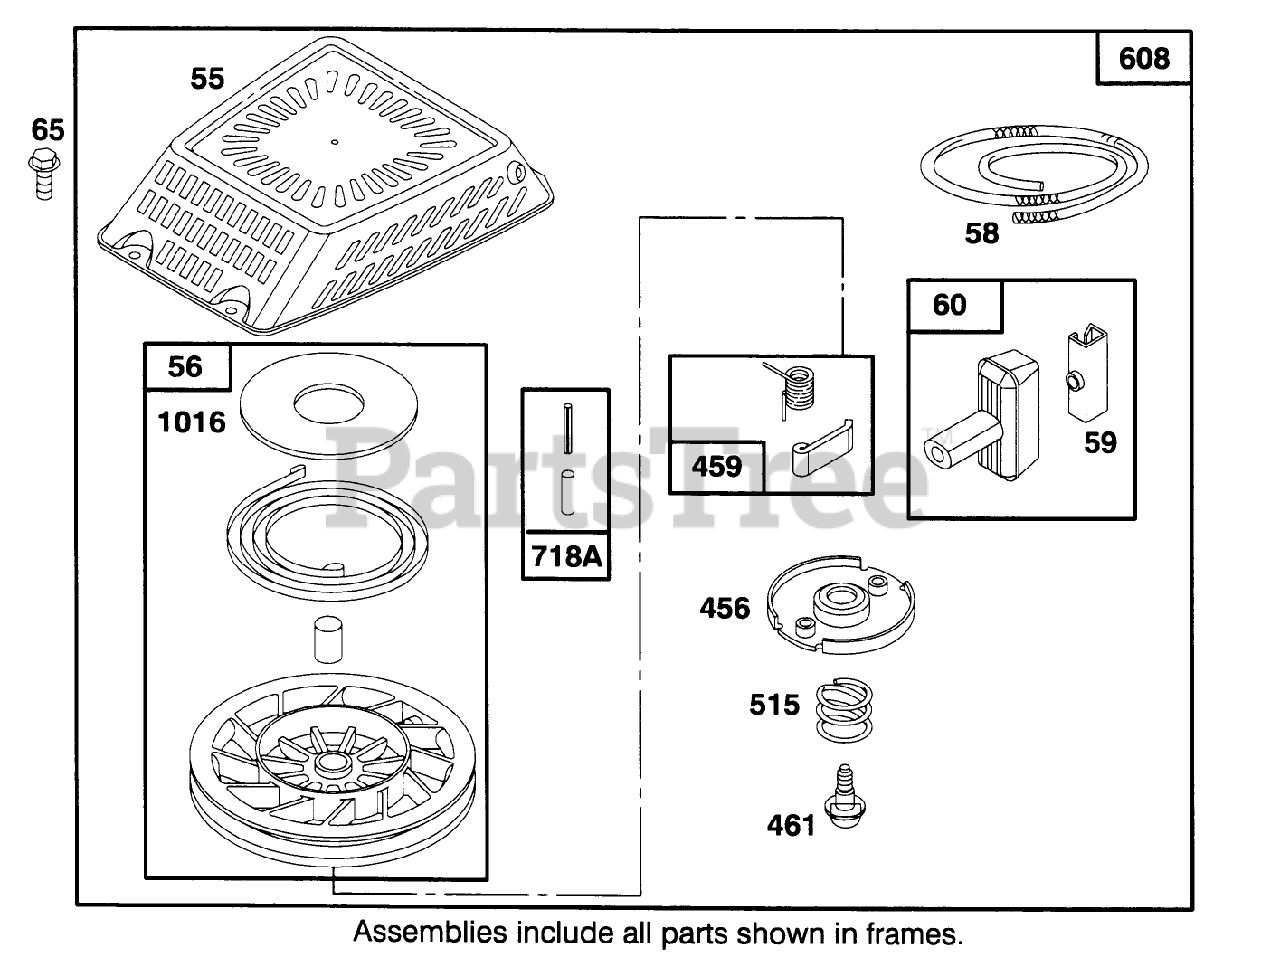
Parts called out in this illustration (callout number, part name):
60	HANDLE-REWIND STARTER
456	RETAINER - SPRING
515	SPRING - RETAINER
